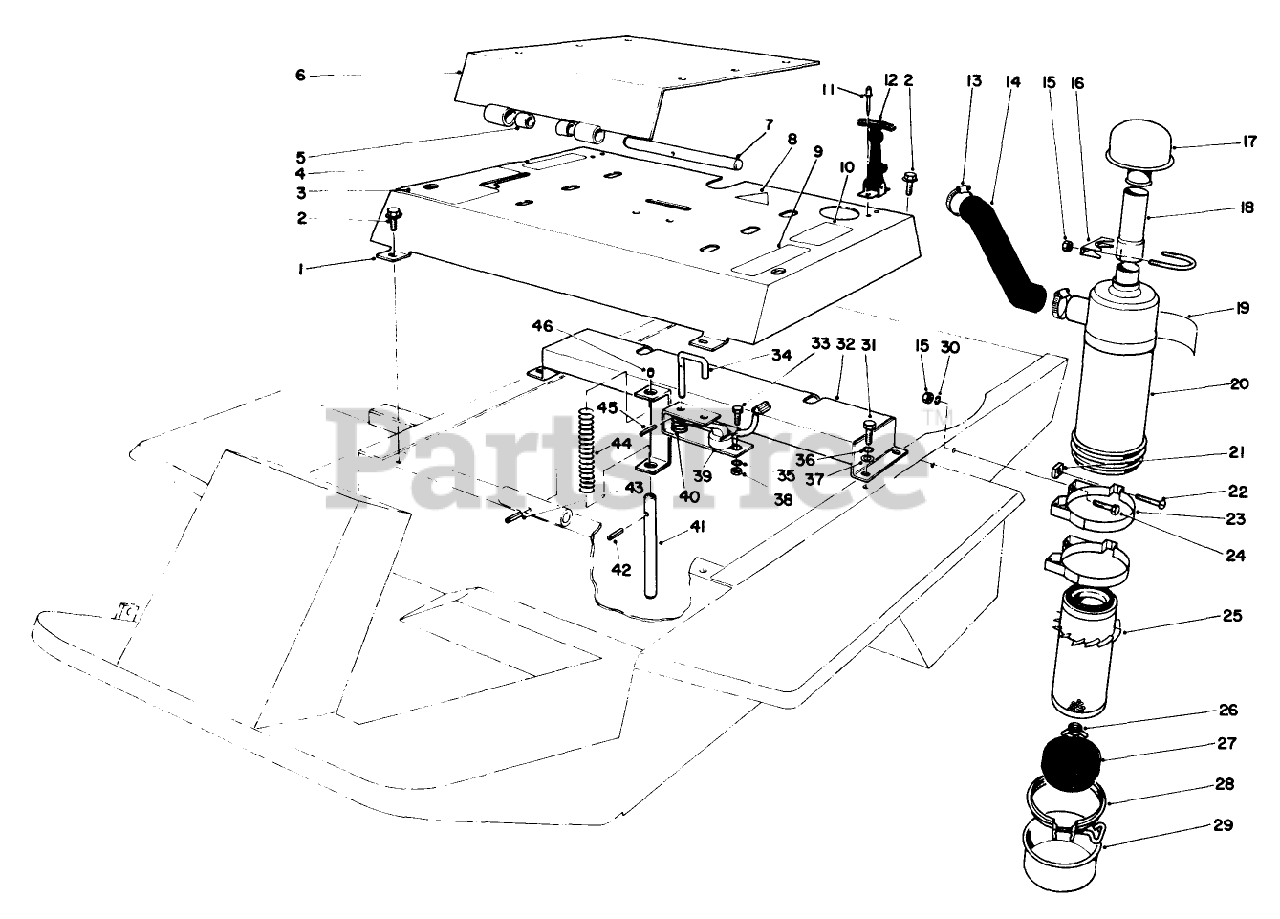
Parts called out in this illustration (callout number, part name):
1	Cover-Support, Seat (Incl. Ref. #4, 5, 9 & 10)
2	SCREW-HHFTF
3	DECAL - LIFT CONTROL
4	DECAL-WARNING
5	.503ID X .875LG BSHG
6	Mounting-Seat (Incl. Ref. #5)
7	SHAFT-PIVOT, SEAT
8	DECAL-DANGER
9	DECAL - CAUTION
10	DECAL-REFUELING
11	RIVET
12	Assembly-Handle
13	CLAMP-HOSE
15	NUT-HEX
16	CLAMP-MUFFLER
18	Tube-Air Cleaner
19	DECAL-INSTALLATION
20	Assembly-Air Cleaner (Incl. Ref. #18 & 24-28)
21	NUT-SQUARE
22	SCREW
23	Assembly-Mounting, Band (Incl. Ref. #20 & 21)
24	SCREW-HH
25	ELEMENT ASM
26	NUT AND GASKET ASM
27	SKIRT-BAFFLE
28	CLAMP ASM
29	A/C CUP ASM
30	WASHER-LOCK
31	SCREW-HH
32	Seat Support
33	SCREW-HH
34	SEAT SWITCH PIN
35	WASHER-LOCK
36	WASHER-LOCK
37	WASHER-FLAT
38	NUT-HEX
39	SWITCH ARM
40	SPRING
41	PIN-SWITCH, SEAT
42	PIN-ROLL, SLOTTED
43	PIN-ROLL, SLOTTED
44	SPRING-COMP
45	PIN-ROLL, SLOT
46	PIN-PEDAL
